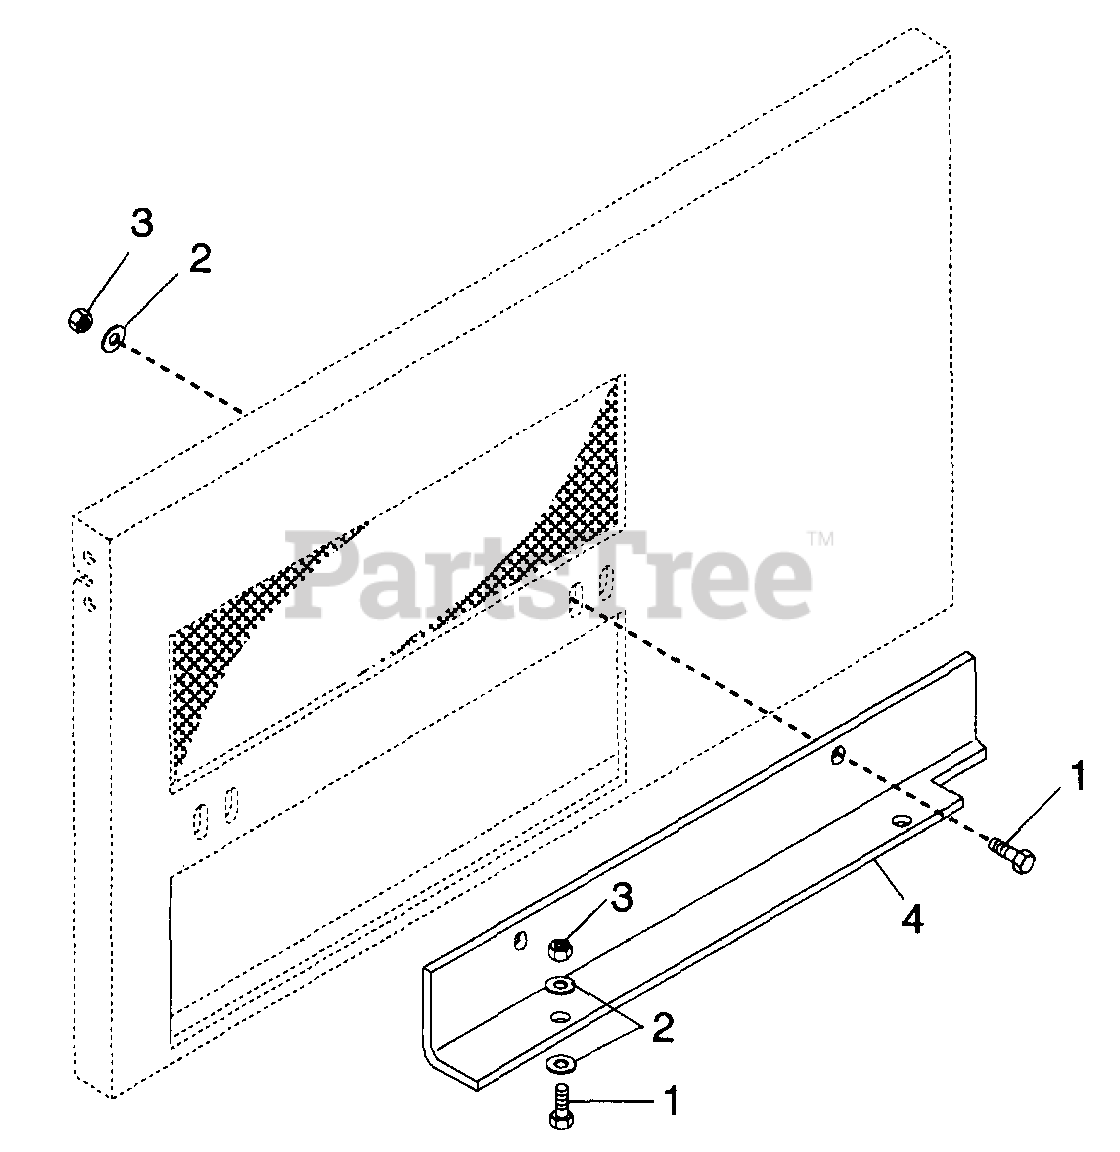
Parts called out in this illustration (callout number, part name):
1	Bolt-Hex .38-16 x 1.00 Grade 5
2	Washer-Flat-Steel .406 x .812 x .065
3	Nut-Locking-Nylon .375-16 Grade 2
4	Adapter, PRO 36
